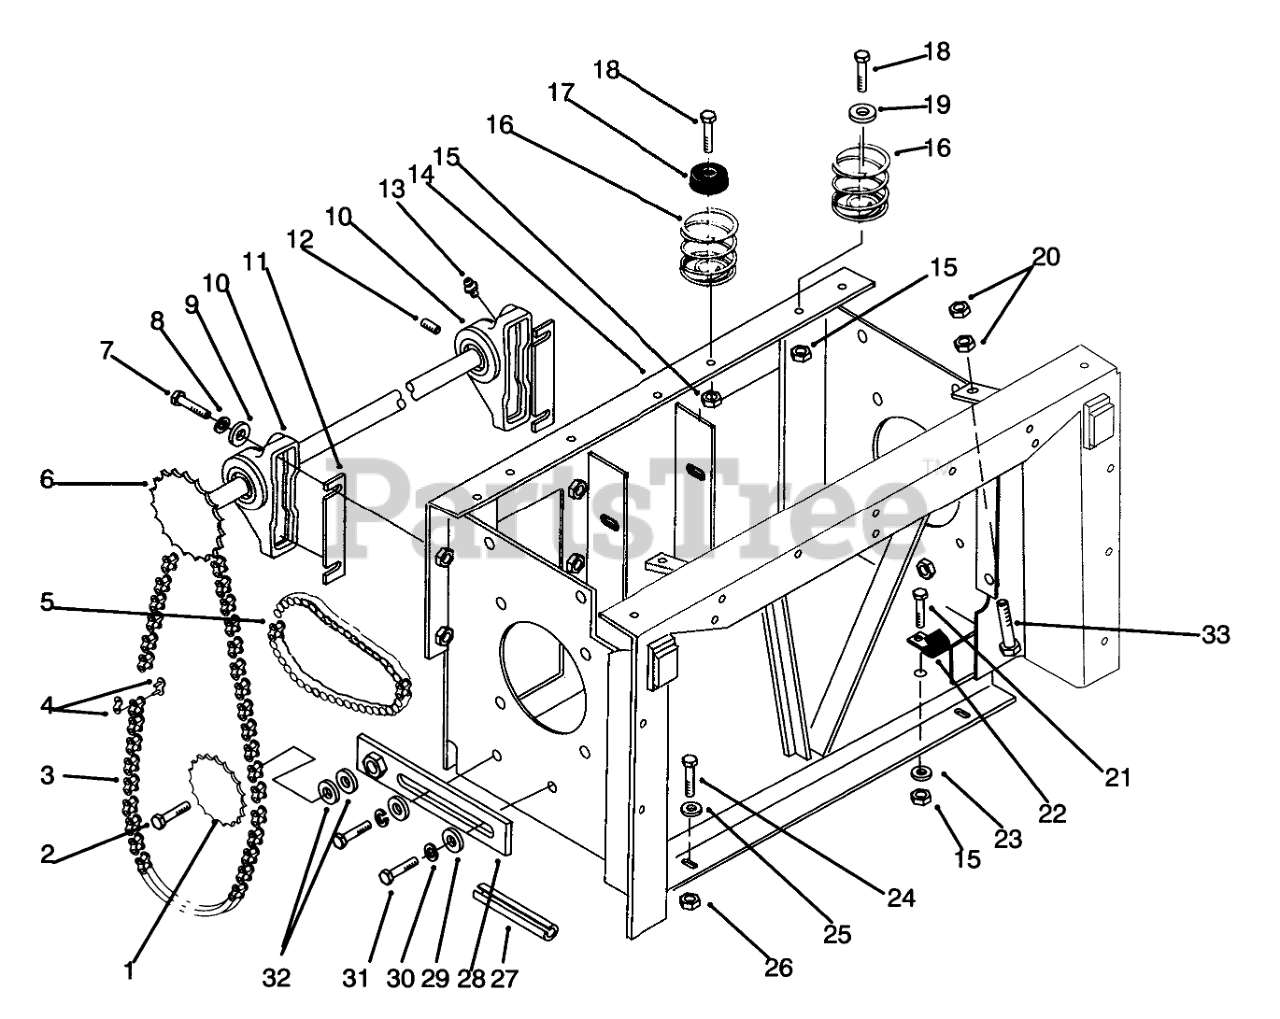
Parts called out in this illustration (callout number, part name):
1	IDLER SPROCKET 20288
2	SCREW-HH
3	ROLLER-CHAIN #50 SEC
4	CONNECTING LINK
5	CHAIN-#50 PRIMARY
6	ASSY-JACKSHAFT PLT
7	SCREW-HH
8	WASHER-LOCK
9	WASHER-FLAT
10	Bearing-Pillow Block (Incl. Ref. #12 & 13)
11	SHIM-PILLOW BLOCK
12	SCREW-HSH
13	FITTING-GREASE
14	WLDMT-FRAME TRANS B
15	NUT-LOCK, NI
16	SPRING-SEAT NYLON
17	BUMPER
18	SCREW-HH
19	WASHER
20	NUT-HEX
21	SCREW-HH
22	CLIP
23	WASHER-PLAIN
24	SCREW-HH
25	WASHER-FLAT
26	NUT-LOCK, NI
27	EDGE TRIM
28	ASSY-CHAIN TENSIO B
29	WASHER
30	WASHER-LOCK
31	SCREW-HH
32	WASHER-FLAT
33	SCREW-HH
